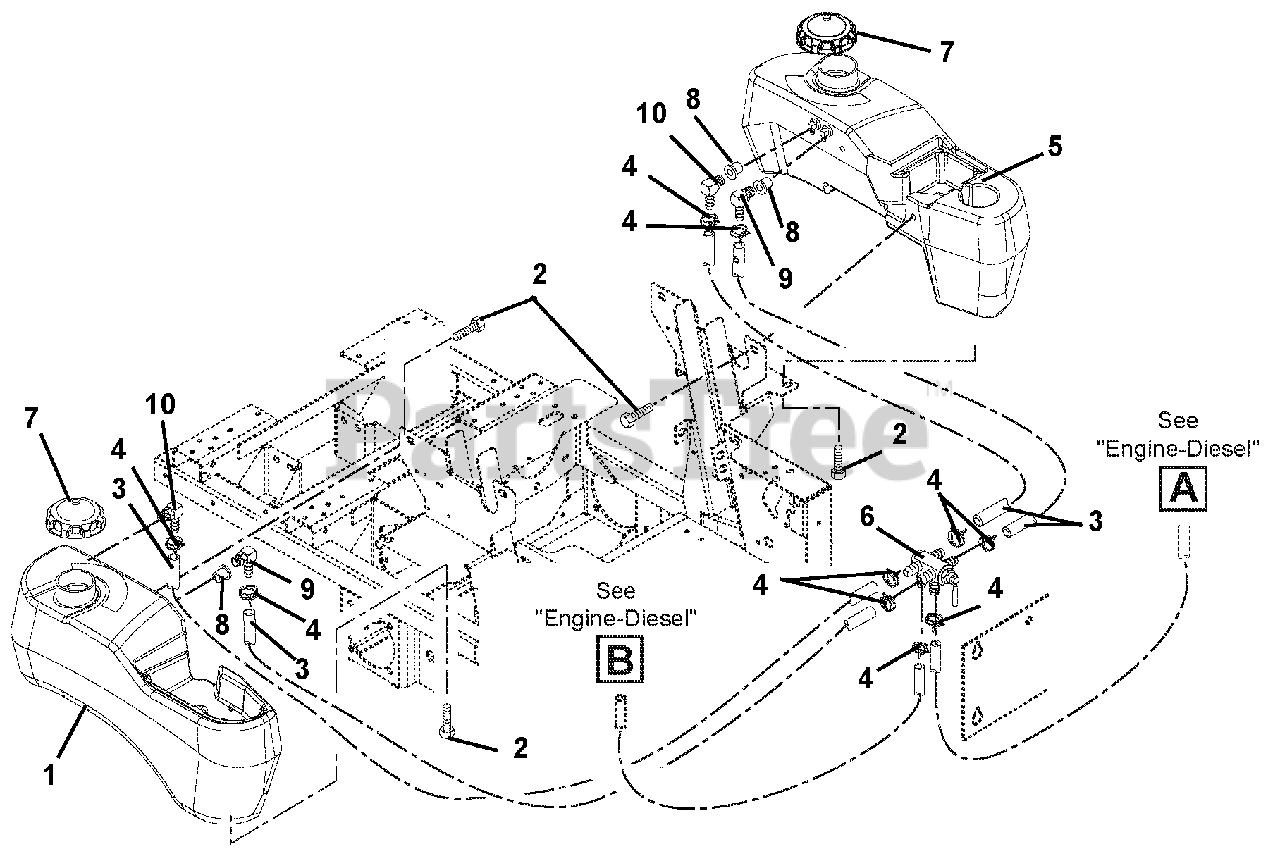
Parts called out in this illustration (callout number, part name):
1	TANK, FUEL-RH(W/RTN)W/O HOSE
2	BOLT, SEMS .31-18 X .62
3	HOSE,5/16 ID
4	CLAMP, HOSE WIRE .520/.550
5	TANK, FUEL-LH(W/RTN)W/O HOSE
6	VALVE, FUEL
7	CAP, FUEL
8	BSHG-FLG .375 X 1.062 X .625 R
8	GROMMET, DAPCO VITON #12240
9	FITTING, TANK ELBOW .31 HOSE
10	FITTING, TANK (5/16 ELBOW)
